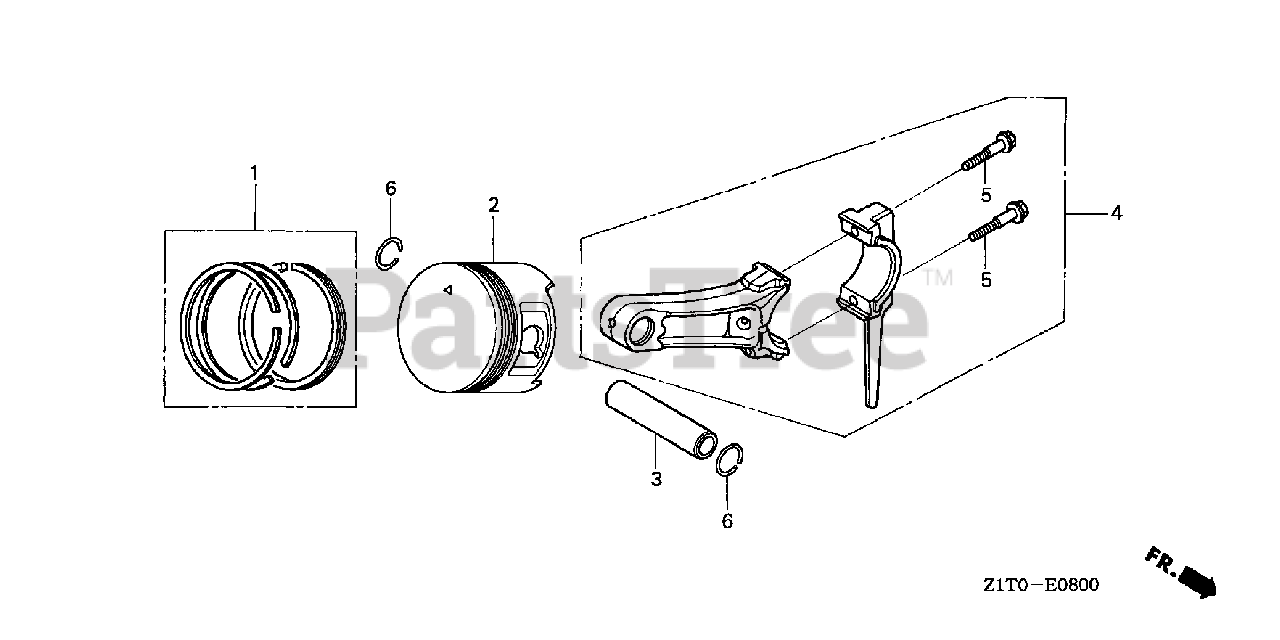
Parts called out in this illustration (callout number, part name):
1	RING SET, PISTON (STD) (TEIKOKU)
1	RING SET, PISTON (STD) (NIPPON)
1	RING SET, PISTON (STD) (RIKEN) (NA USE ALT:13010-ZL0-003)
1	RING SET, PISTON (STD) (RIKEN)
1	RING SET, PISTON (0.25) (TEIKOKU)
1	RING SET, PISTON (0.25) (NIPPON)
1	RING SET, PISTON (0.50) (TEIKOKU)
1	RING SET, PISTON (0.50) (NIPPON)
1	RING SET, PISTON (0.50) (RIKEN)
1	RING SET, PISTON (0.75) (TEIKOKU)
1	RING SET, PISTON (0.75) (NIPPON)
2	PISTON (STD)
2	PISTON (0.25)
2	PISTON (0.50)
2	PISTON (0.75)
3	PIN, PISTON
4	ROD ASSY., CONNECTING
5	BOLT, CONNECTING ROD
6	CLIP, PISTON PIN (18MM)
